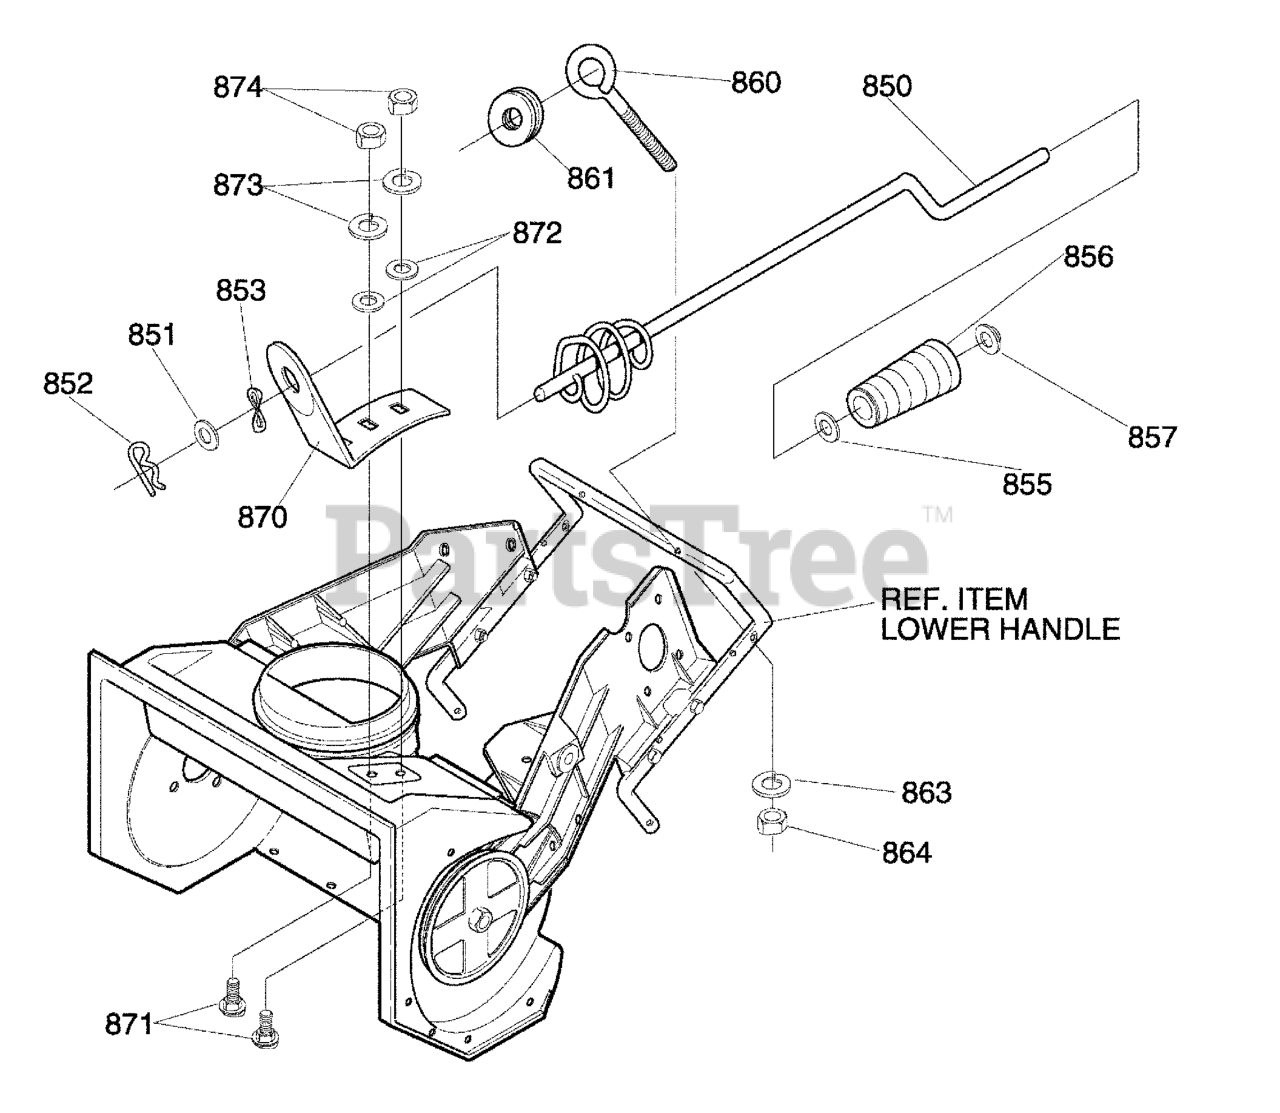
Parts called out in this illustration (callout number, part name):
850	ROD, ASSY UPPER CHUTE CONTROL
851	WASHER, FLAT .406X.81X.066
852	PIN, COTTER .094 DIAX1.00LG
853	WASHER, CURVED SPRING
855	WASHER, FLAT .406X.81X.066
856	KNOB, SLEEVE
857	NUT, PUSH
860	BOLT, EYE 3/8-16X2.00
861	GROMMET, EYE BOLT
863	WASHER, MDSPTLK
864	NUT, 3/8-16 HEXJAM
870	BRACKET, CHUTE ROTATE
871	BOLT, 5/16-18X.75 CARR.
872	WASHER, FLAT .349X.69X.066
873	WASHER, HVSPTLK .328 x .60 x .09
874	NUT, 5/16-18 REGHEX
